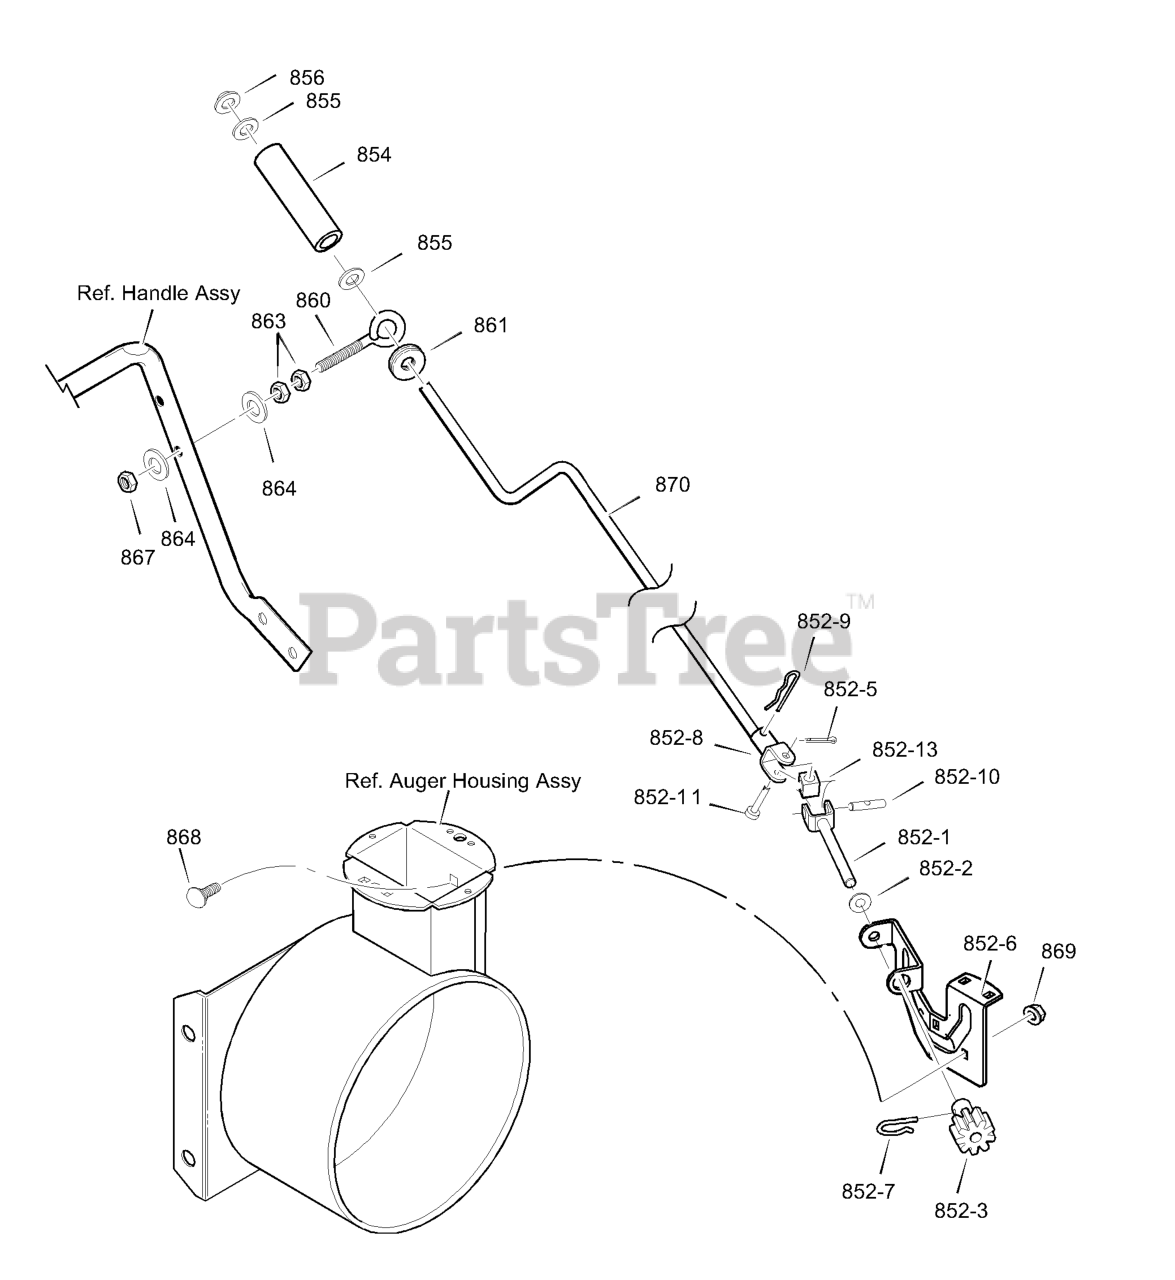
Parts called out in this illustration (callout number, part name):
852-1	ASSEMBLY, YOKE & ROD
852-2	WASHER, CURVED SPRING
852-3	GEAR, CHUTE ROTATION 9T
852-5	PIN, COTTER
852-6	BRACKET, GEAR MOUNT
852-7	PIN, HAIR
852-8	ASSEMBLY, YOKE ADAPTER YZ
852-9	PIN, HAIR
852-10	PIN, UNIVERSAL JOINT
852-11	PIN, CLEVIS
852-13	HOUSING, UNIVERSAL
854	KNOB, SLEEVE
855	FLATWASHER
856	NUT, PUSH ON 3/8"
860	EYE BOLT 3/8-16X6.00
861	GROMMET, EYE BOLT
863	NUT, 3/8-16 HEXJAM
864	FLATWASHER .406X.81X.066
867	NUT, 3/8-16 HEXNYL
868	BOLT, CARRIAGE 1/4-20 X 1.00
869	NUT
870	CRANK, ASSY CHUTE
